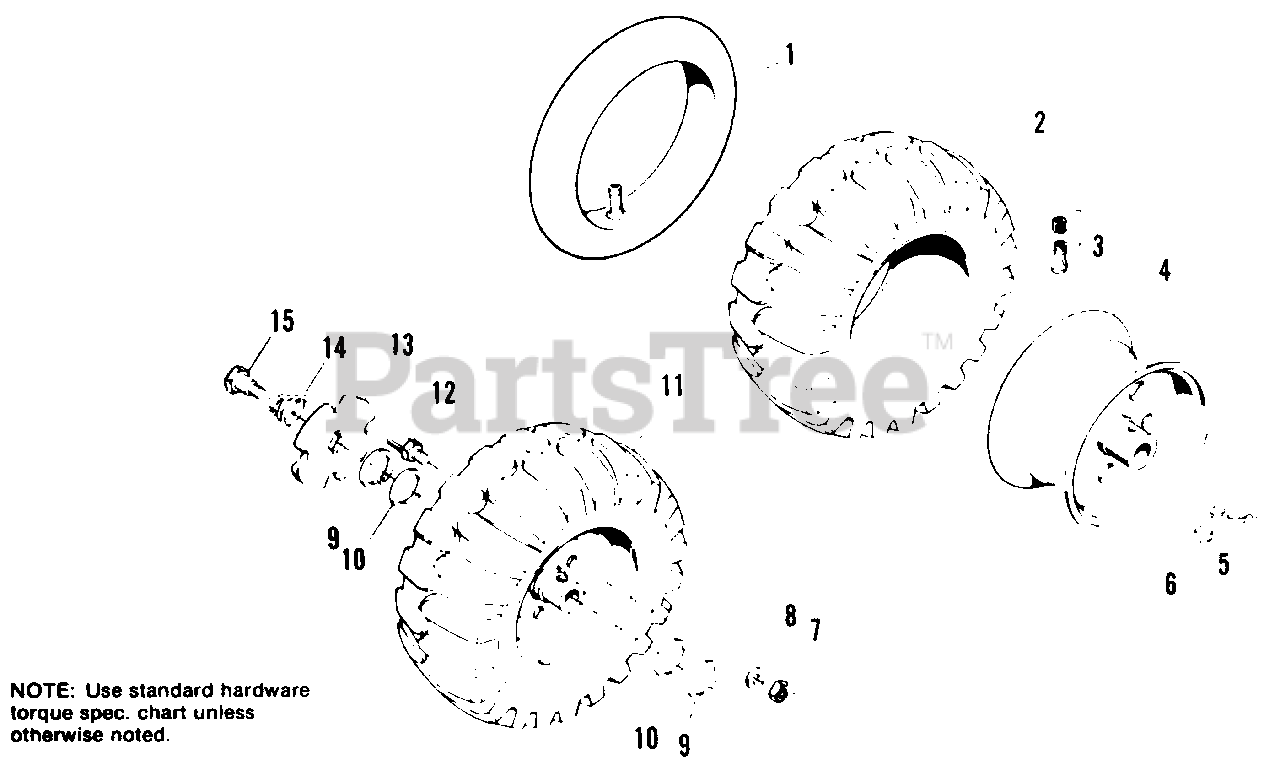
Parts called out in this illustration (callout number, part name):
2	TIRE, Tubeless, Knobby
3	VALVE STEM & CAP
4	WHEEL & HUB ASSY.
5	CLIP, Spring
6	PIN, Clevis
7	LOCKNUT, Hex, 3/8-16
8	WASHER, Plain, 5/16
9	RING, Retaining
10	WASHER, Special
11	WHEEL & TIRE ASSY.
15	BOLT, Shoulder
